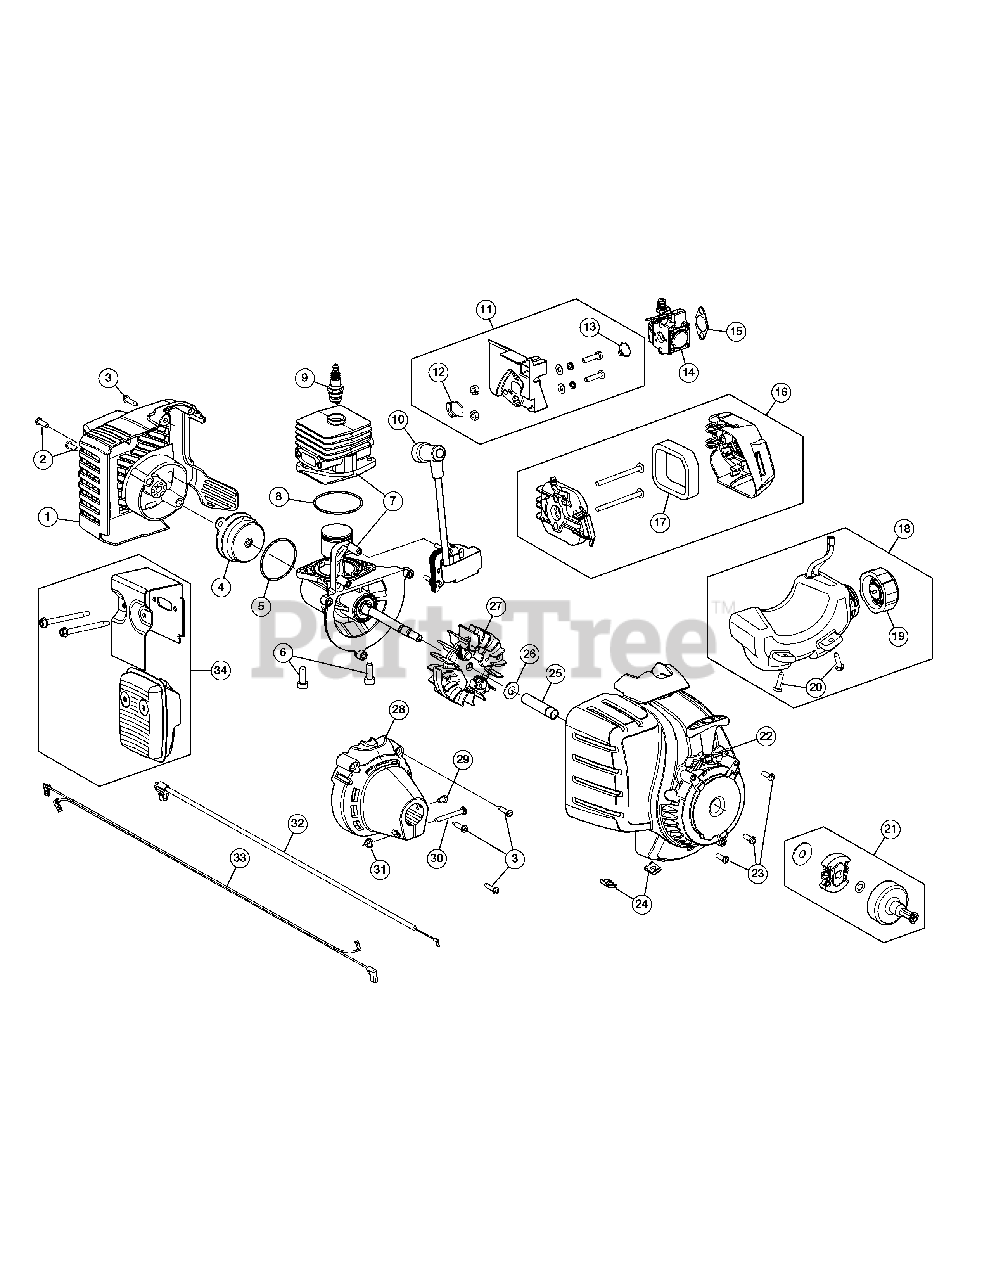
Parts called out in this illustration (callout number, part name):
1	Rear Cover Assembly (Incl. 2 & 3)
2	Rear Housing Screw
3	Cover Screw
4	Electric Starter Cover Assembly
5	O-Ring
6	Crankcase Bolt
7	Short Block Assembly (Incl. 5, 6, 8 - 10 & 25 - 27)
8	Crankcase O-Ring
9	Spark Plug
10	Module Assembly
11	Insulator Assembly (Incl. 12 & 13)
12	Insulator O-Ring
13	Carburetor O-Ring
14	Carburetor
15	Air Cleaner Gasket
16	Aircleaner Cover Assembly (Incl. 17)
17	Aircleaner Filter
18	Fuel Tank Assembly (Incl. 19 & 20)
19	Fuel Tank Screw
20	Fuel Tank Cap
21	Clutch Assembly
22	Starter Housing (Incl. 23 & 24)
23	Housing Screw
24	U-shaped Nut
25	Spacer
26	Washer
27	Flywheel Assembly
28	Clutch Cover (Incl. 3)
29	Anti-rotation Screw
30	Clamp Screw
31	Clamp Nut
32	Throttle Cable
33	Lead Wires
34	Muffler Assembly
